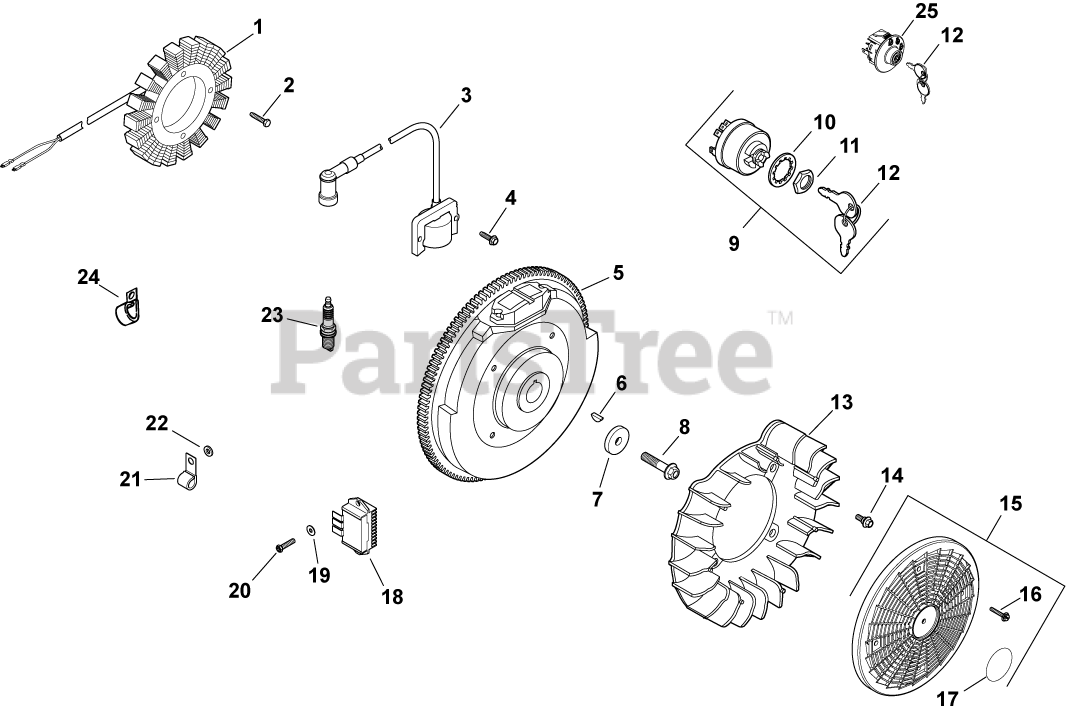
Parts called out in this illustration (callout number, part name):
1	KIT, 15 / 20 AMP STATOR
2	SCREW, M5X0.8X25 - (#25086402S)
3	KIT, MODULE IGNTN (CDI FIXED)
4	SCREW, FLG THD FRM M5X.8X20-(#25086399S)
5	FLYWHEEL, PAINTED-USE 24 025 55-S
6	KEY, 3/16" X 5/8"
7	WASHER, FLAT 13/32"
8	SCREW, FLG M10X1.5X45 - (#25086361S)
9	SWITCH ASSY, KEY (KM)-USE 25 099 32-S
10	WASHER, INTERNAL TOOTH
11	NUT, KEY SWITCH
12	KEY, SET -USE 48 340 01-S
13	FAN USE 24 755 253-S
14	BOLT, SHOULDER
15	KIT, GRASS SCREEN
16	SCREW, FLG SEMS M4X.7X25
17	DECAL, GRASS SCREEN USE 24 113 499-S
18	REG/RECTIFIER (20/25 AMP)-USE 25 403 20-
19	WASHER, FLAT 7/32"
20	SCREW, HEX FLANGE HI-LO
21	CLIP, CABLE
22	WASHER, FLAT 1/4" (O.D. 1/2")
23	PLUG, SPARK (PRO SERIES)
24	CLIP, TUBE & WIRING (KM)
25	KIT, KEY SWITCH (SNAP-IN)
